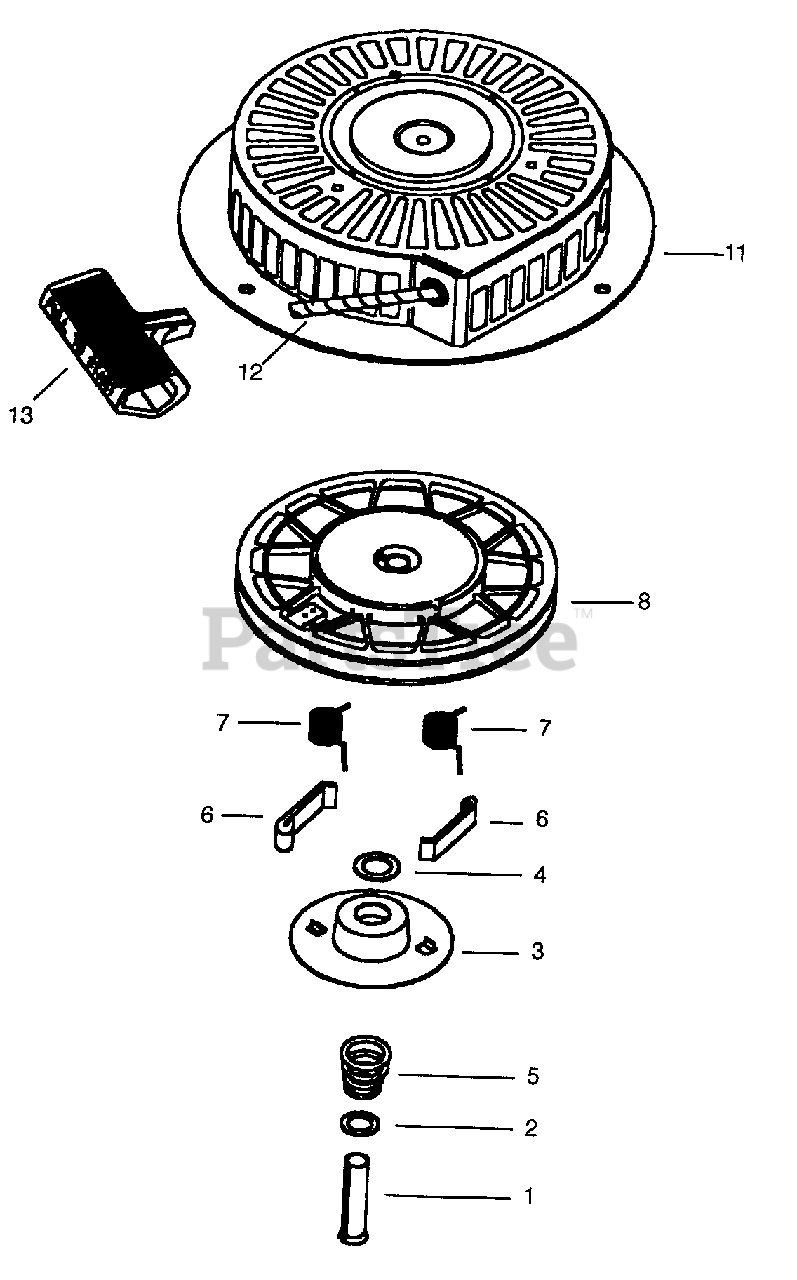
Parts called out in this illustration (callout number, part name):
1	Spring Pin
5	Brake Spring
6	Starter Dog
7	Dog Spring
8	Pulley & Rewind Spring Assy
11	Starter Housing Assy
12	Starter Rope
13	Starter Handle
